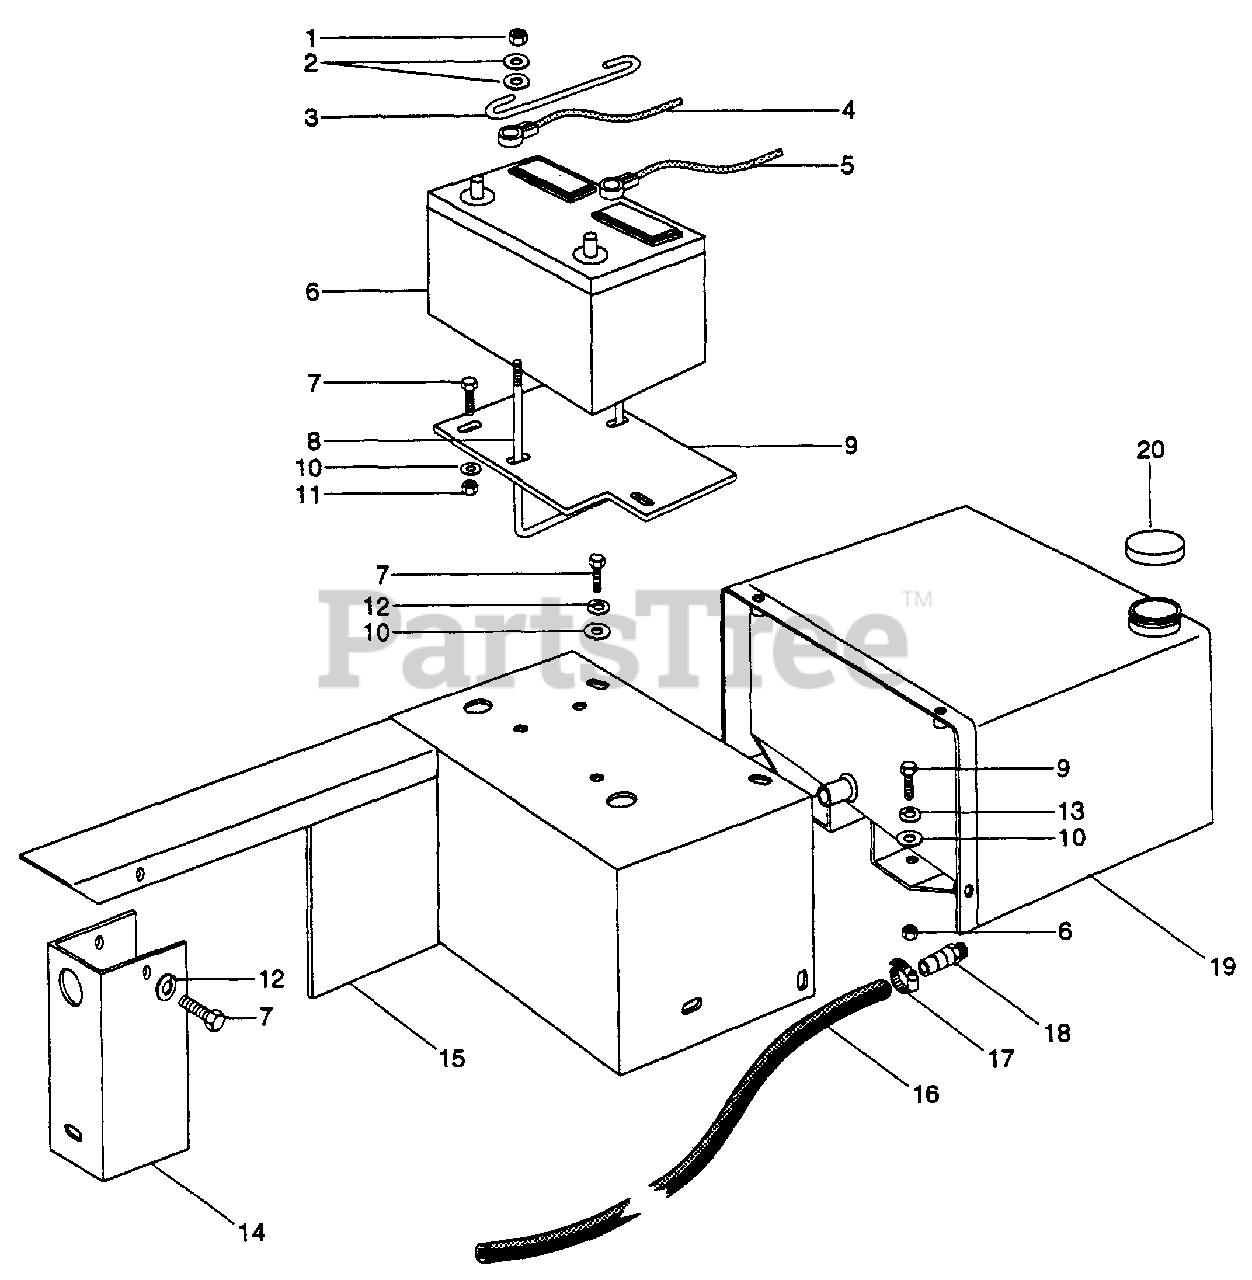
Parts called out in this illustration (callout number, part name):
1	NUT-LK-NYL .250-20 PL
2	WSHR-FL-STL .281 X .62 X .065 PL
3	ROD, HOLD DOWN
4	BATTERY CABLE
5	GROUND CABLE
6	BATTERY
7	BLT-HEX .38-16 X 1.00 PL GR
8	ROD BATTERY
9	MOUNTING PLATE
10	WSHR-FL-STL .438 X 1.0 X .083 PL
11	NUT-LK TOP .375-16 GR C PL
12	WSHR-LOCK .375 X .115 HVY PL
13	WSHR-FL-STL .38 X .875 X .083 PL
14	HOUR-METER MOUNT
15	GUARD WELDMENT
16	HOSE, FUEL
17	CLAMP HOSE
18	HOSE BARB
19	FUEL TANK WELDMENT
